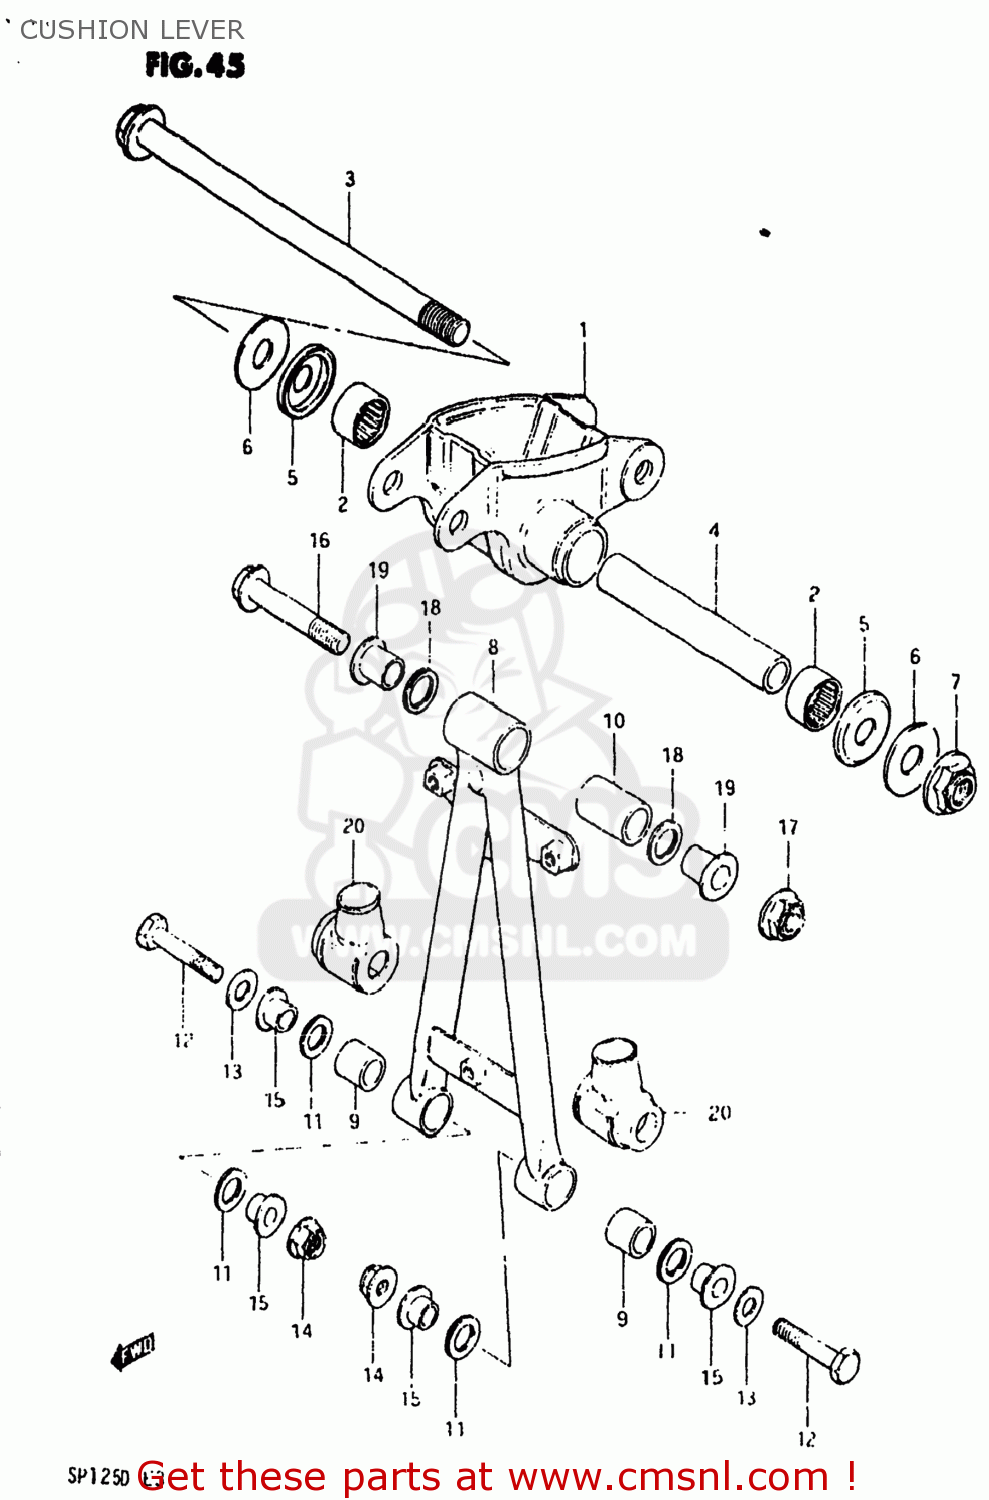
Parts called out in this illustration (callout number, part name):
1	LEVER SET,REAR CUSHION
2	BEARING(17X25X20)
3	SHAFT,REAR CUSHION LEVER
4	SPACER
5	DUST SEAL,RR CUSHION LEVER
6	WASHER
7	NUT 12MM
8	ROD SET,REAR CUSHION LEVER
9	BUSHING
10	BUSH,UPPER
11	DUST SEAL,RR CUSHION LOD LWR
12	BOLT,REAR CUSHION ROD
13	WASHER
14	NUT
15	SPACER,RR CUSHION ROD LWR
16	BOLT(10X65)
17	NUT
18	DUST SEAL,LEVER CUSHION UNIT
19	SPACER,RR CUSHION ROD UPR
20	BOOT,REAR CUSHION ROD,LOWER
